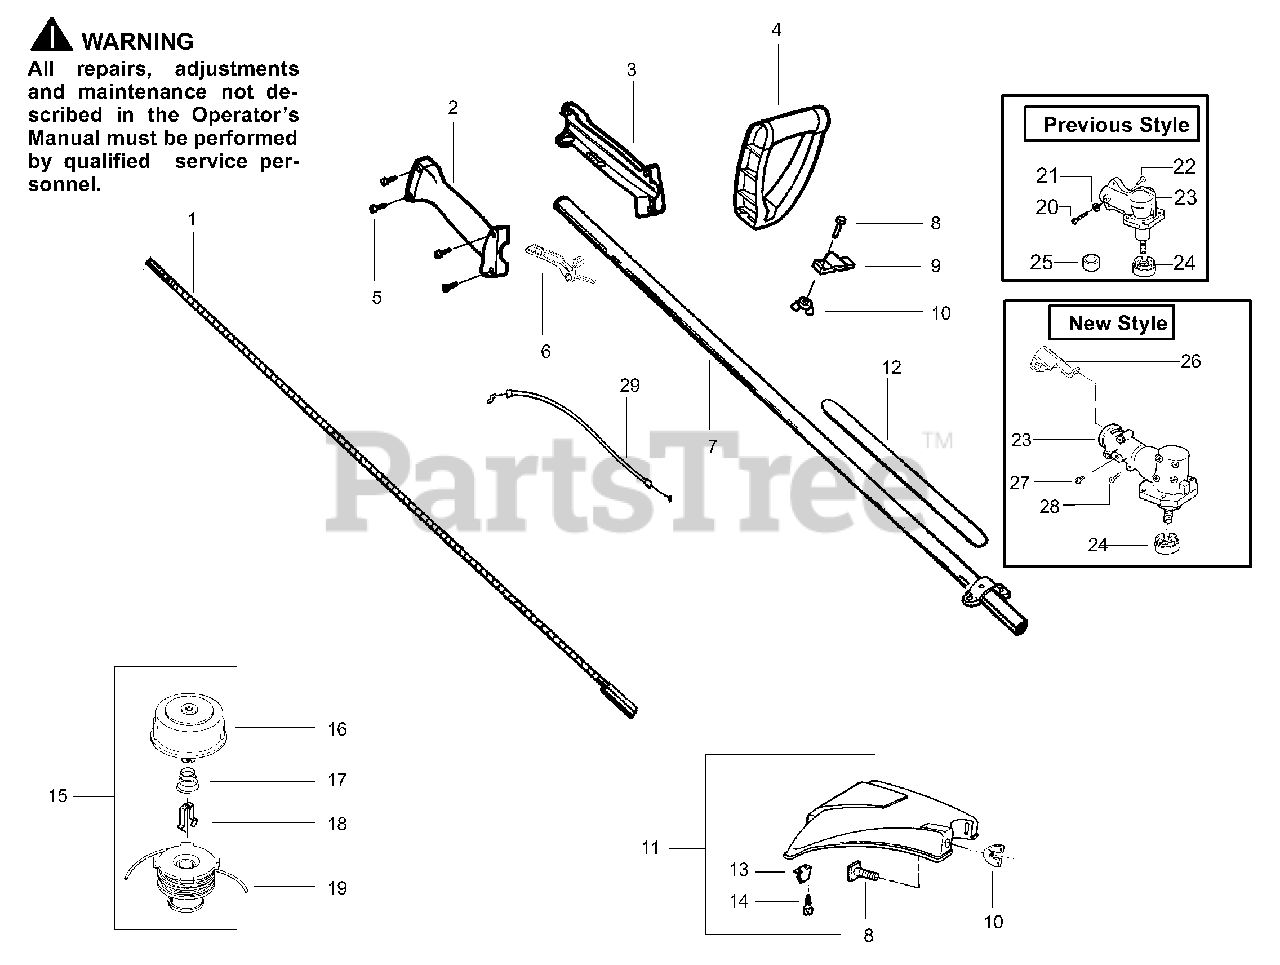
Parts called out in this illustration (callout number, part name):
1	Shaft-Flex-52"
2	Hsg. - Throttle (Right)
3	Hsg. - Throttle (Left)
4	Handle-Assist
5	Screw-Throttle Hsg.
7	Assy-Drive Shaft
9	Clamp-Handle
10	Wingnut
11	Kit-Shield Ass'y.
12	Decal-Shaft Warning
13	Line Limiter
14	Screw-Line Limiter
15	Accy-Cutting Head Ass'y.
16	assy-Hub
17	Spring-Return
18	Retainer-Spool
19	Spool w/Line
20	Screw-Gear Box
21	Lockwasher-Gear Box
22	Screw-Gear Box/Shield
23	Kit-Gear Box Assy.
24	Dust Cup
25	Seal Sleeve
26	Bracket-Shield
29	Assy-Throttle Cable
